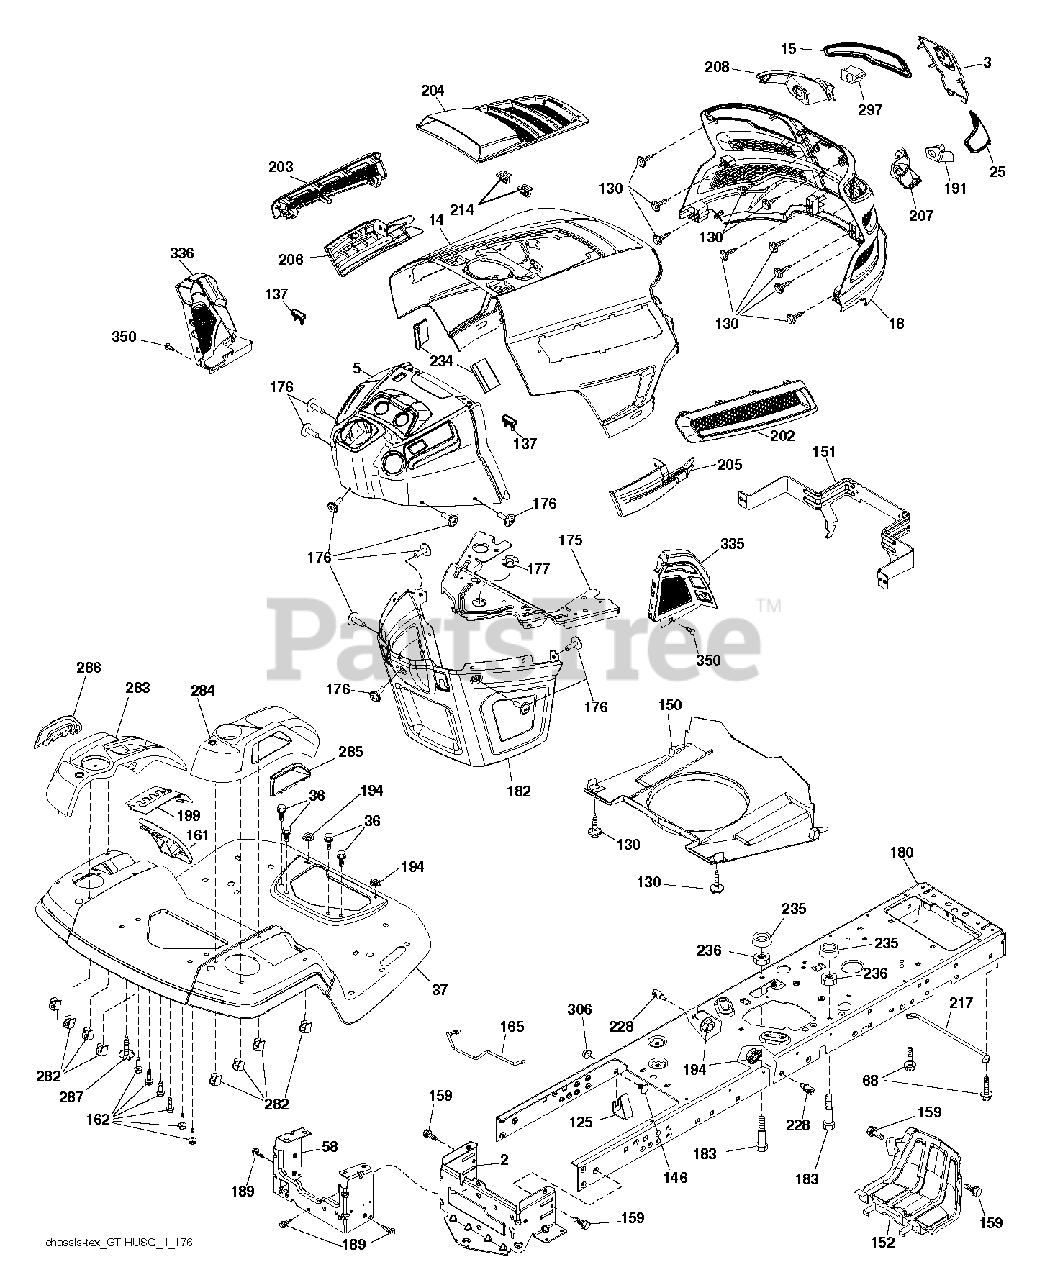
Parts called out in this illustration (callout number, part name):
2	DRAWBAR.LOWER.2PC.18/22
3	APPLIQUE.SUBASM.GT.HUSQ.II
5	DASH.UPP.GT2.DUAL.RD.PTO.MCHOK
14	HOOD.ASM.HUSQVARNA.GT.TEX.ORAN
15	LENS.HEADLIGHT.LH.GTII.2011
18	GRILLE.SUBSTRATE.2011.
25	LENS.HEADLIGHT.RH.GTII.2011
36	SCREW 5/16"
37	FENDER.TLT.FS.W/CPH/FW/RSF.668
58	DRAWBAR UPPER 2PC SMALL FENDER
68	SCREW LT
125	CLIP.FUEL.LINE
130	SCREW.#10 X 0.750.BOS
137	BUMPER DASH
146	BOLT.RDHD.SHT.SQNK.3/8-16X5/8
150	AIR.DUCT.GTV.BLACK
151	BRACKET.PIVOT.HOOD.GT.HUSQ.II
152	SHIELD.BROWNING.PNT.GT.V2
159	SCREW, 3/8-16X3/4
161	WINDOW.FUEL.LT.HUSQ.TEX.498
162	SCREW.HI-LO.CONSOLE
165	SUPPORT.TANK.REAR.B/TE
175	PLATE.CROSSMEMBER.HUSQ
176	SCREW.#10-24X5/8.RN.QU
177	BUSHING STEERING
180	CHASSIS.TEX.BOLTED
182	DASH.LOWER.COMMON.12V.ADAPTOR
183	BOLT.5/16-18X1-1/4 FULL THD
189	SCREW
191	INSERT.REFLECTIVE.RH.HUSQ.GTII
194	NUT LOCK HEX FLANGE 5/16-18
199	PLATE.DECK.LIFT.HUSQ.LT
202	VENT.SIDE.RH.GT.HUSQ.II.
203	VENT.SIDE.LH.GT.HUSQ.II.498
204	VENT.TOP.HUSQ.GT2
205	SIDE.TRIM.RH.GT.HUSQ.II
206	SIDE.TRIM.LH.GT.HUSQ.II.GRAY
207	BEZEL LIGHT.RH.GT.II.MYLAR
208	BEZEL LIGHT.LH.GT.II.MYLAR
214	CLIP.RETAINER.TINNER.
217	ROD.PIVOT.HOOD
228	STUD.FASTNER.W/ANTI-ROTATE
234	BUMPER.HOOD.TEX.HUSQVARNA
235	SPACER FENDER
236	NUT.CENTERLOCK.5/16-
282	CLIP.RETAINER.CONSOLE.LT.HUSQ
283	CONSOLE.DECK.LIFT.R.SDFL.HUSQ
284	CONCOLE.CNTRL.PDL.HUSQ.LT.498
285	CONSOLE INSERT RH
286	CONSOLE.INSRT.LH.HUSQ.LT.BLACK
287	SCREW 1/4X20
297	INSERT.REFLECTIVE.LH.HUSQ.GTII
306	NUT LOCK FLG 3/8-16 UNC
335	COVER.LOWER.DASH.RH.BLACK
336	COVER-LH.LOWER.DASH.GT2.BLACK
350	CLIP.X-MAS.TREE
